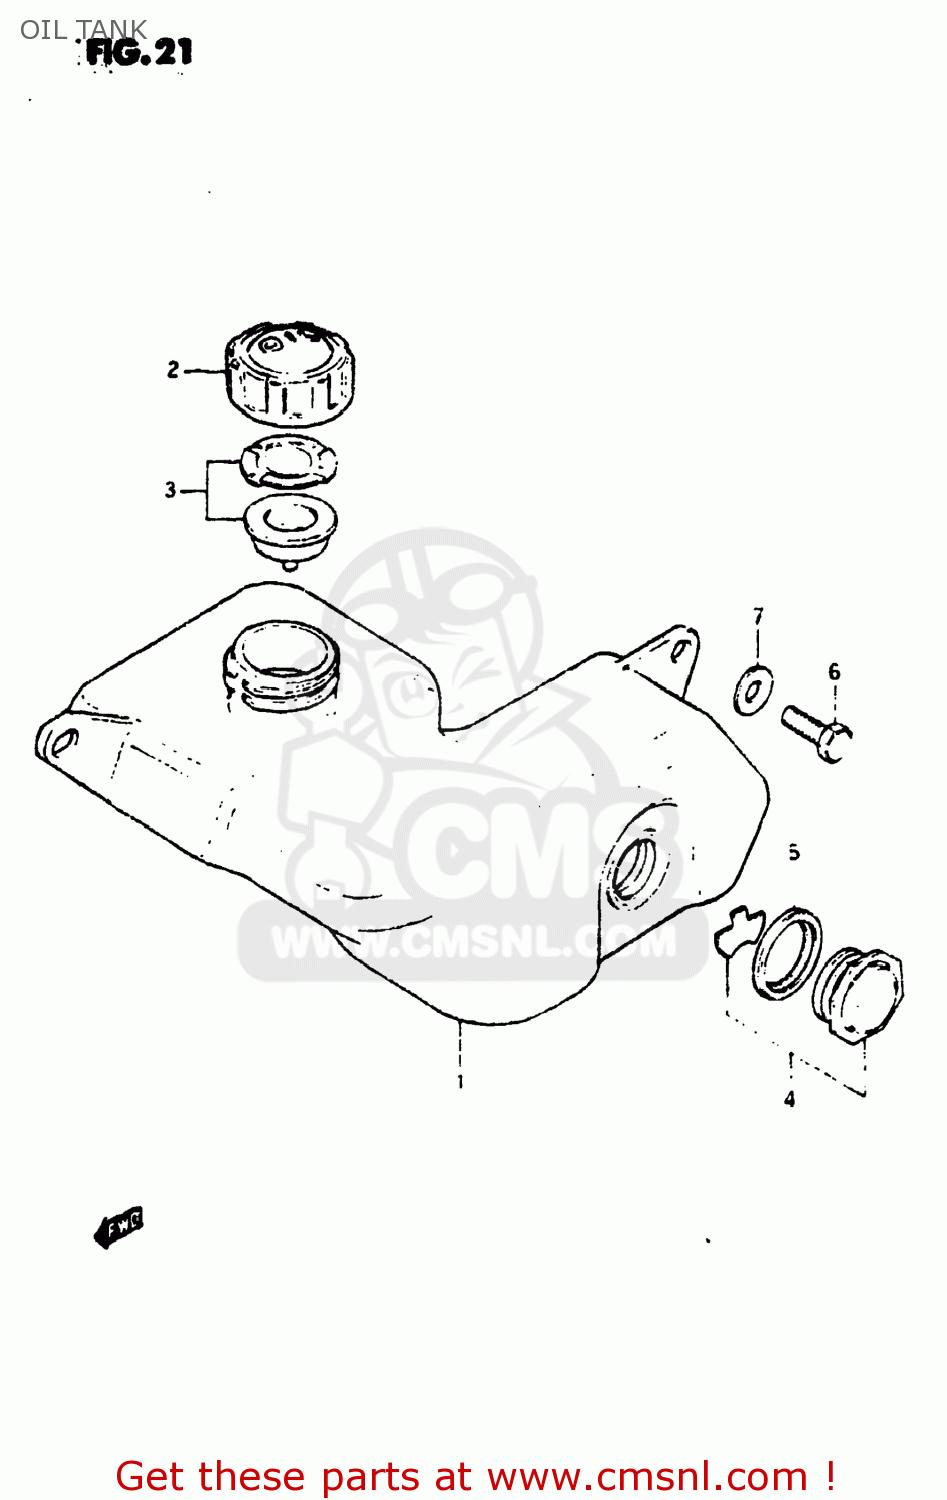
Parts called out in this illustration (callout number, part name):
1	TANK,OIL
2	CAP,OIL TANK
3	GASKET SET (NAS)
4	LENS SET,OIL LEVEL
5	GASKET (NAS)
6	BOLT, UPPER
7	WASHER
